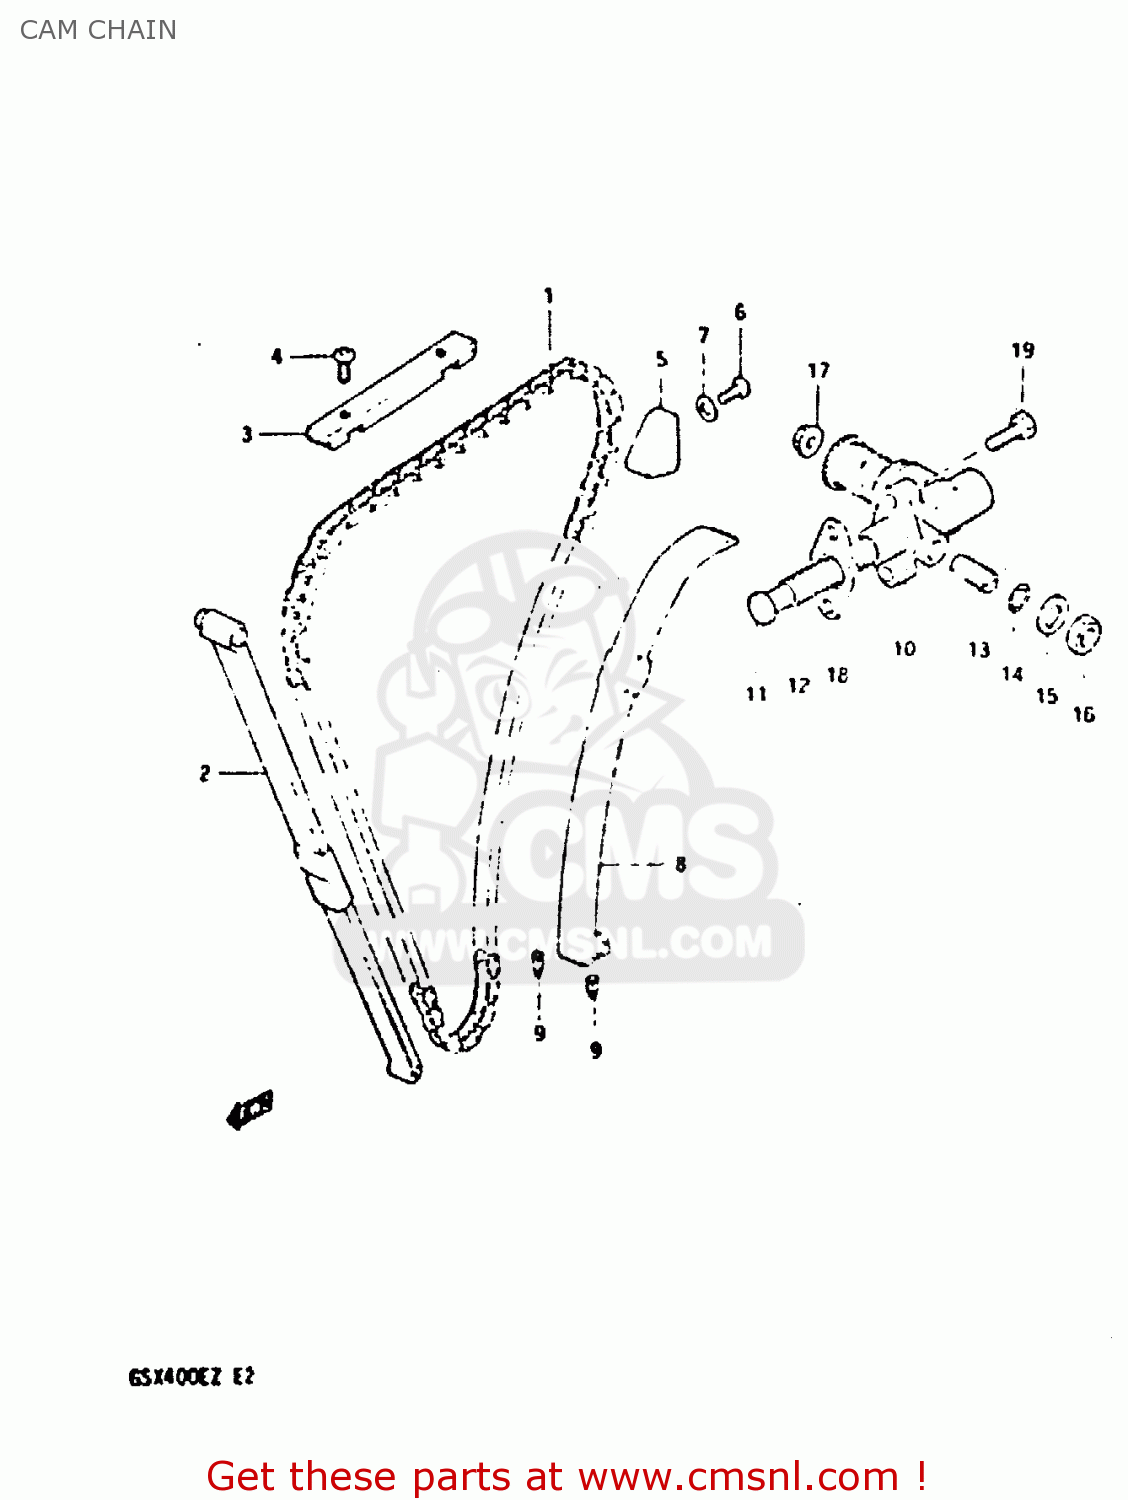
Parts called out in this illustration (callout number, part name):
1	CHAIN,CAMSHAFT DRIVE(120L)
2	GUIDE, CAM CHAIN NO.1
3	GUIDE,CAM CHAIN NO.3
4	SCREW
5	GUIDE,CAM CHAIN
6	SCREW 6X12
7	GASKET (NAS)
8	TENSIONER,CAM CHAIN
9	CUSHION,CAM CHAIN TENSIONER
10	ADJUSTER ASSEMBLY,TENSIONER
11	ROD,PUSH
12	SPRING
13	SCREW
14	O-RING
15	WASHER
16	NUT
17	NUT
18	GASKET,TENSIONER ADJUSTER (MCA)
19	SCREW (6X25)
